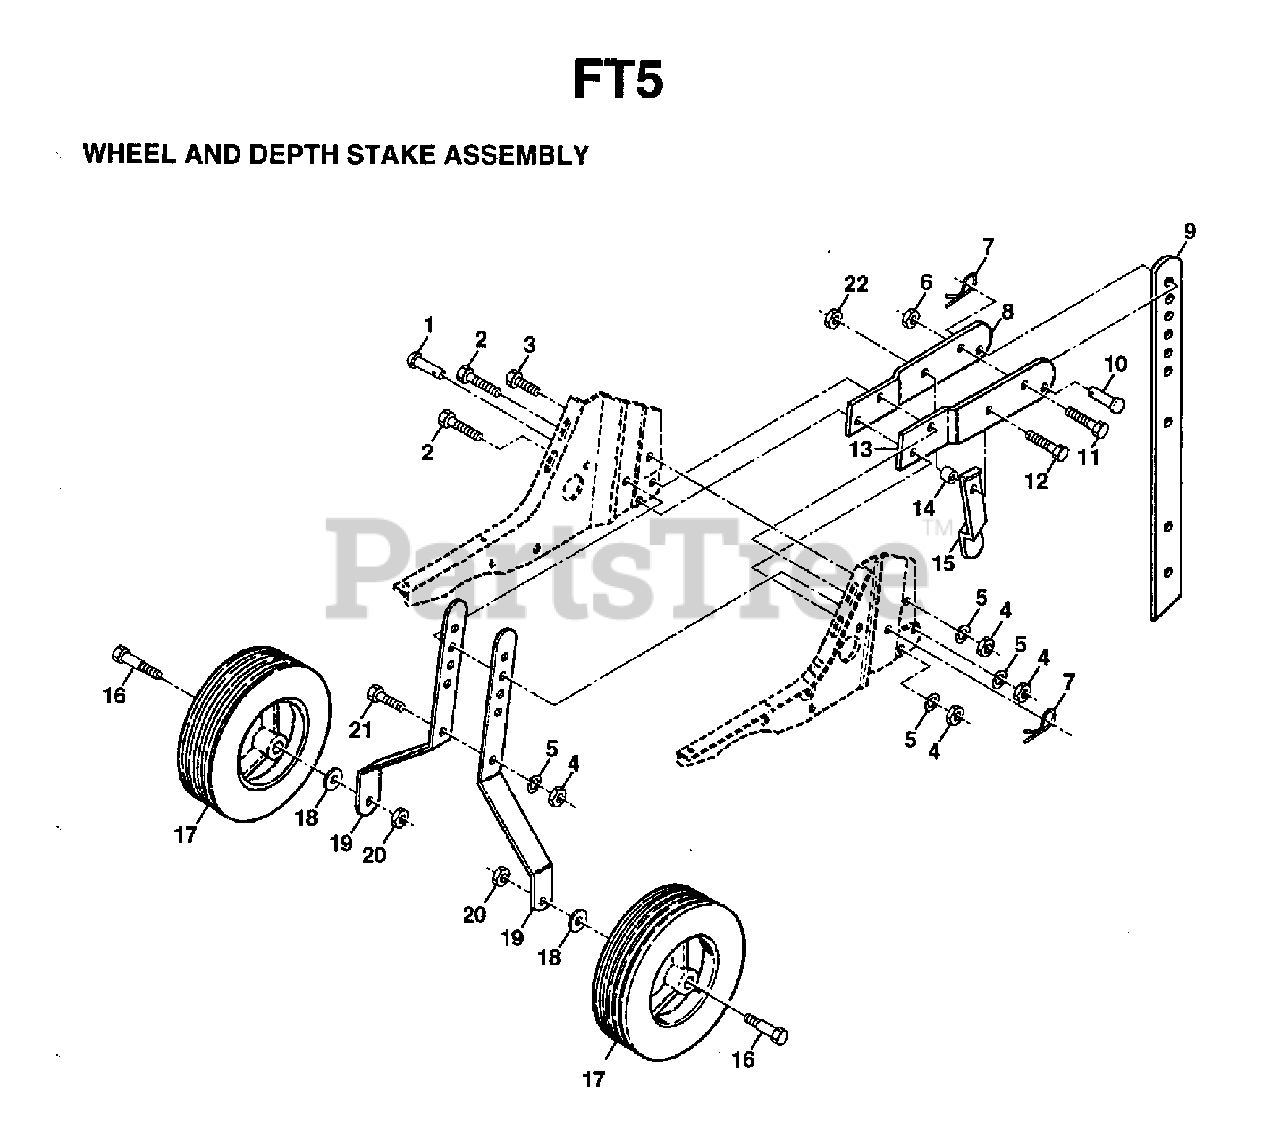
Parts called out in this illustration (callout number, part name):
1	PIN
2	BOLT
3	BOLT
5	LOCKWASHER
6	NUT
7	SPRING.RETAINER
8	SUPPORT.STAKE.RH.BLACK
9	RP STAKE.DEPTH.13.25.W/9HOLES
11	BOLT
12	BOLT
16	BOLT.SHOULDER
18	WASHER
20	LOCKNUT
21	BOLT RB
22	NUT.71038.31-18.HEX.NYLOCK
